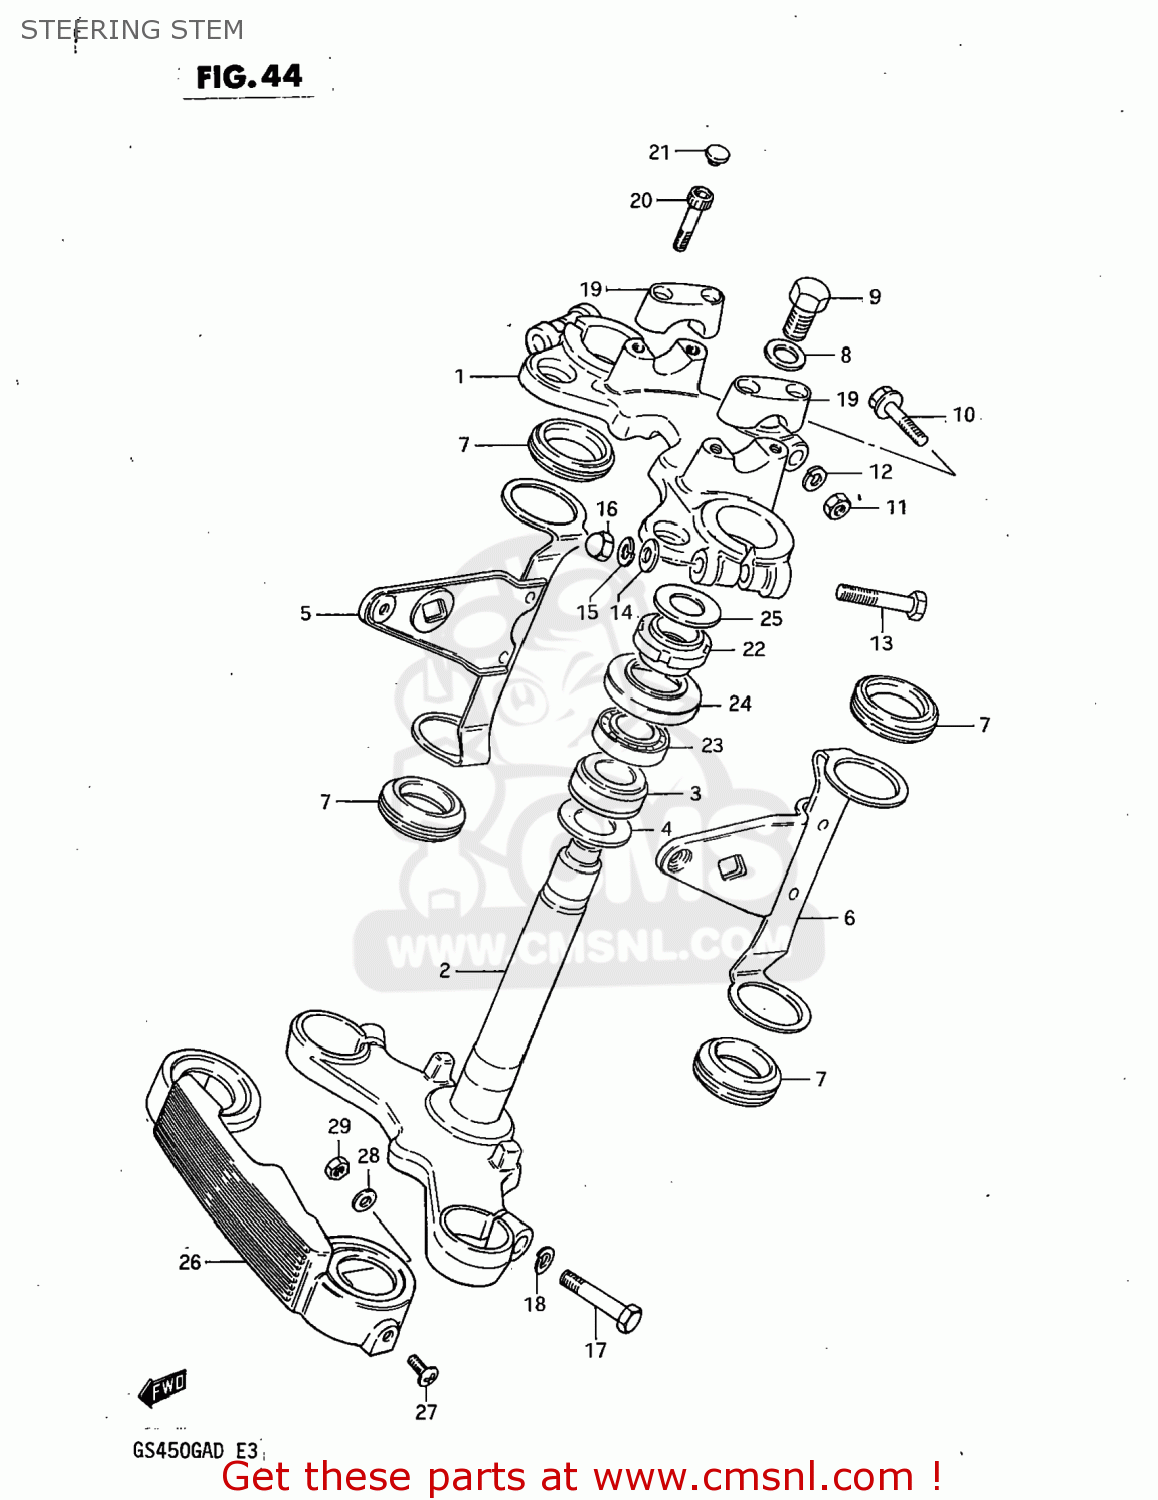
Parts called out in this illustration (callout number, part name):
1	HEAD,STEERING STEM
2	STEM,STEERING
3	BEARING
4	WASHER,THRUST
5	BRACKET,HEADLAMP,RIGHT
6	BRACKET,HEADLAMP,LEFT
7	CUSHION,HEADLAMP BRACKET
8	WASHER
9	BOLT(12X20)
10	BOLT
11	NUT
12	LOCK WASHER
13	BOLT 10X55
14	WASHER
15	LOCK WASHER
16	NUT
17	BOLT 10X40
18	LOCK WASHER
19	HOLDER,HANDLEBAR(BLACK)
20	BOLT
21	CAP(OD:14.5)
22	NUT,STEERING STEM
23	TAPER,ROLLER BEARING
24	DUST SEAL,STEERING UPR
25	WASHER(18.5X24X1)
26	COVER,FRONT FORK
27	SCREW
28	WASHER
29	NUT
